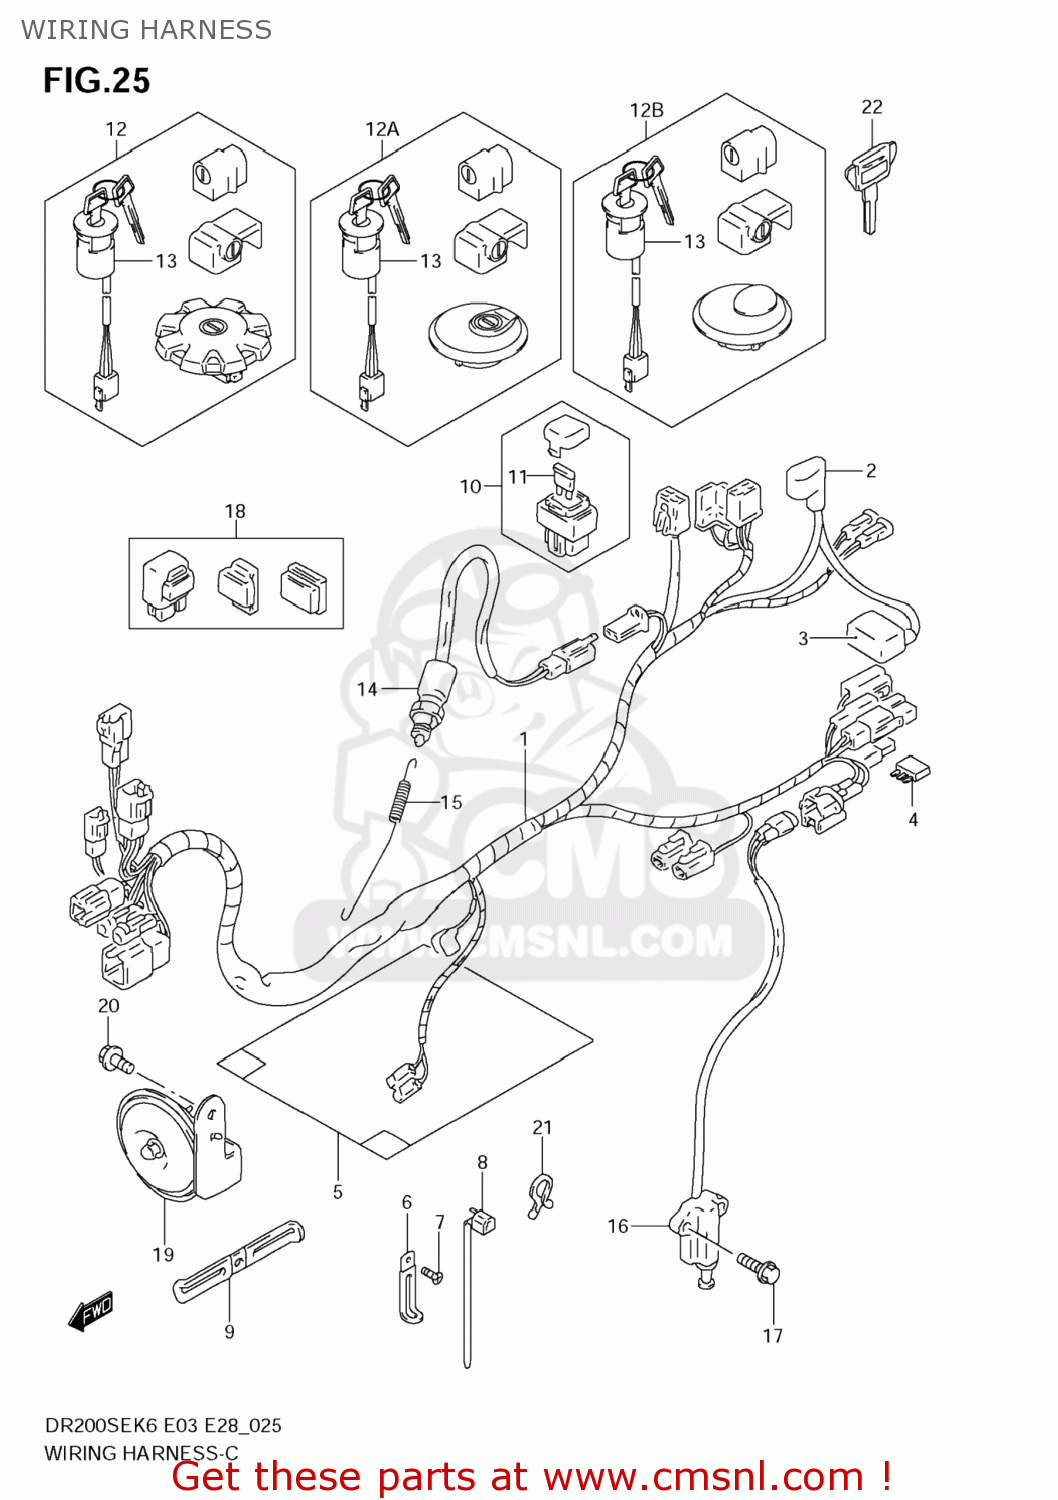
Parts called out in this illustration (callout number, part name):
1	HARNESS,WIRING
2	CAP,STARTER RELAY
3	CAP,BATTERY PLUS
4	DIODE(STANLEY DE8804)
5	COVER,WIRING HARNESS
6	CLAMP(L:45)
7	SCREW
8	CLAMP(L:95)
9	CLAMP,STARTER MOTOR LEAD
10	BOX ASSY,FUSE
11	FUSE(20A)
12	LOCK SET
12A	LOCK SET
12B	LOCK SET
13	SWITCH ASSEMBLY,IGNITION
14	SWITCH ASSY,STOP LAMP
15	SPRING
16	SWITCH ASSY,SIDE STAND
17	BOLT
18	RELAY ASSY
19	HORN ASSY
20	BOLT
21	CLIP(ID:11.5)
22	KEY,BLANK(TYPE:C)
